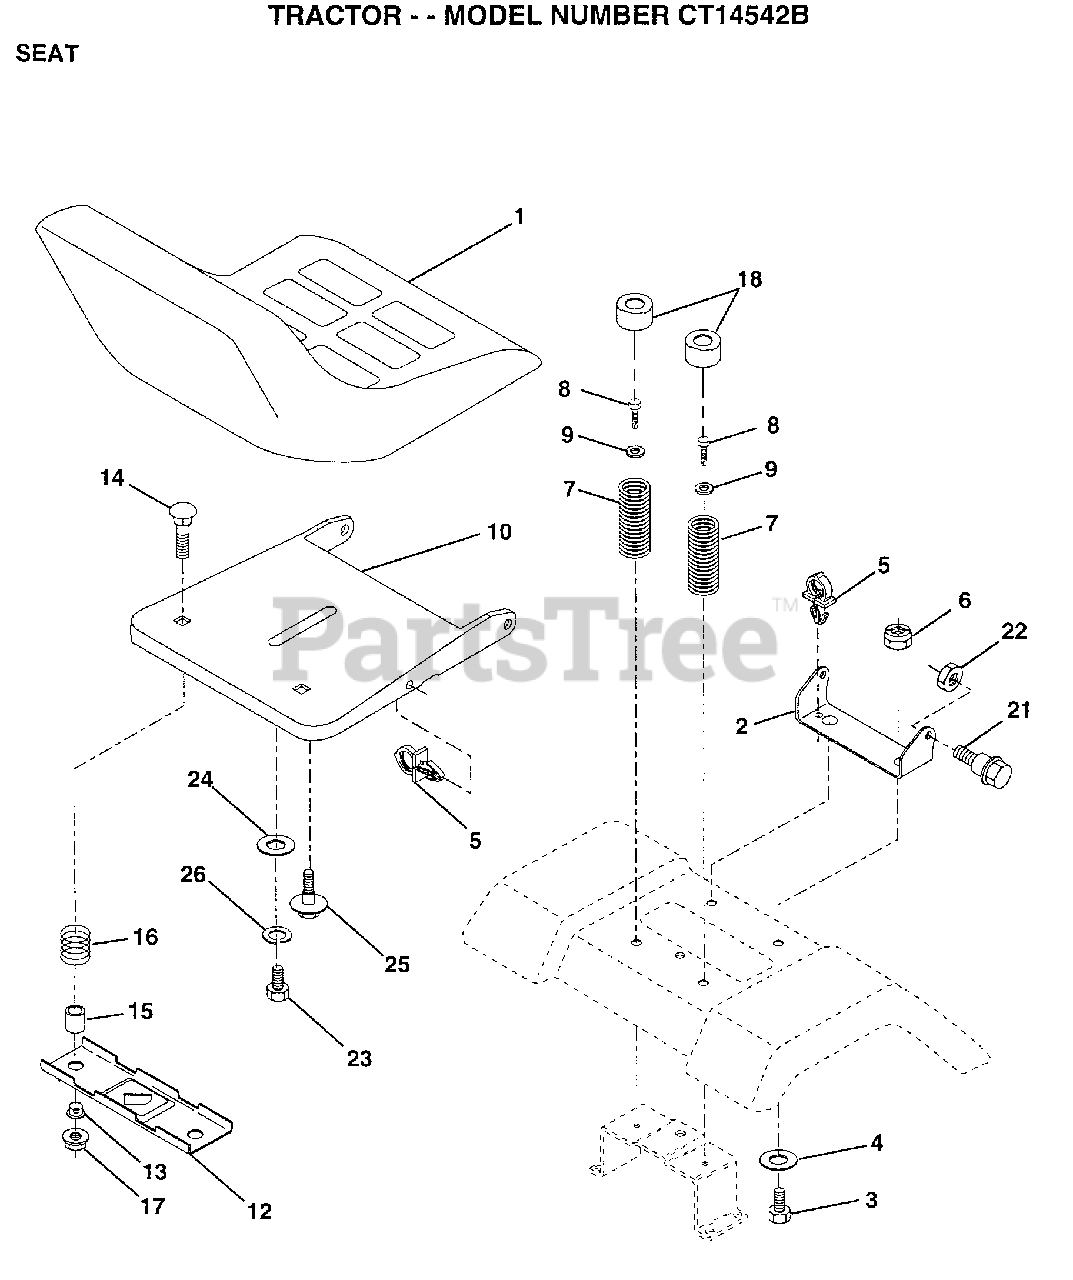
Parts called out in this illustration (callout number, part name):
2	BRACKET PVT SEAT
3	BOLT
4	WASHER PM
5	CLIP.PUSH-IN.HING
6	NUT
7	SPRING COMPRESSIO
8	SCREW GTV
9	WASHER
11	"KNOB 1/2"" YT"
12	BRKT SWITCH
13	BUSHING
15	SPACER SPLIT
16	SPRING COMPRESSED
21	"BOLT,SHOULDER"
24	WASHER
25	"BOLT,SHOULDER"
